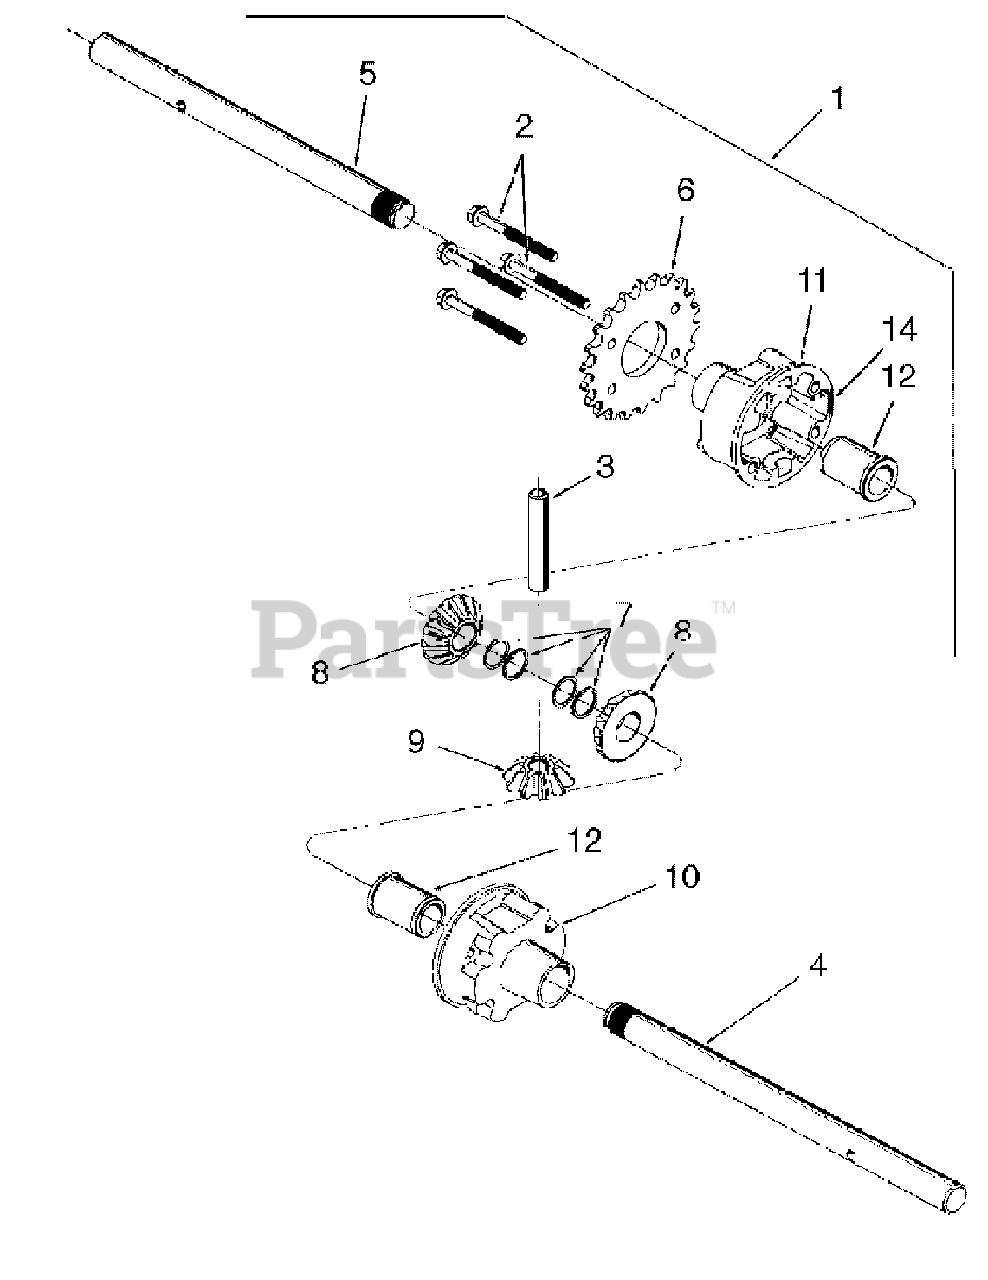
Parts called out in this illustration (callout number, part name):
1	Differential Ass'y Complete
2	Screw, Hex Wash Hd Tapp 1/4-20 x 2-5/16
3	Cross Shaft
4	Axle Shaft, .75 x 10.95
5	Axle Shaft, .75 x 9.82
6	Sprocket, 22T
7	Ring, Retaining
8	Gear, Differential, 14T
9	Gear, Differential, 10T
10	Housing, Differential RH
11	Housing, Differential LH
12	Bearing, Flange, .75 ID x 1.0 OD
